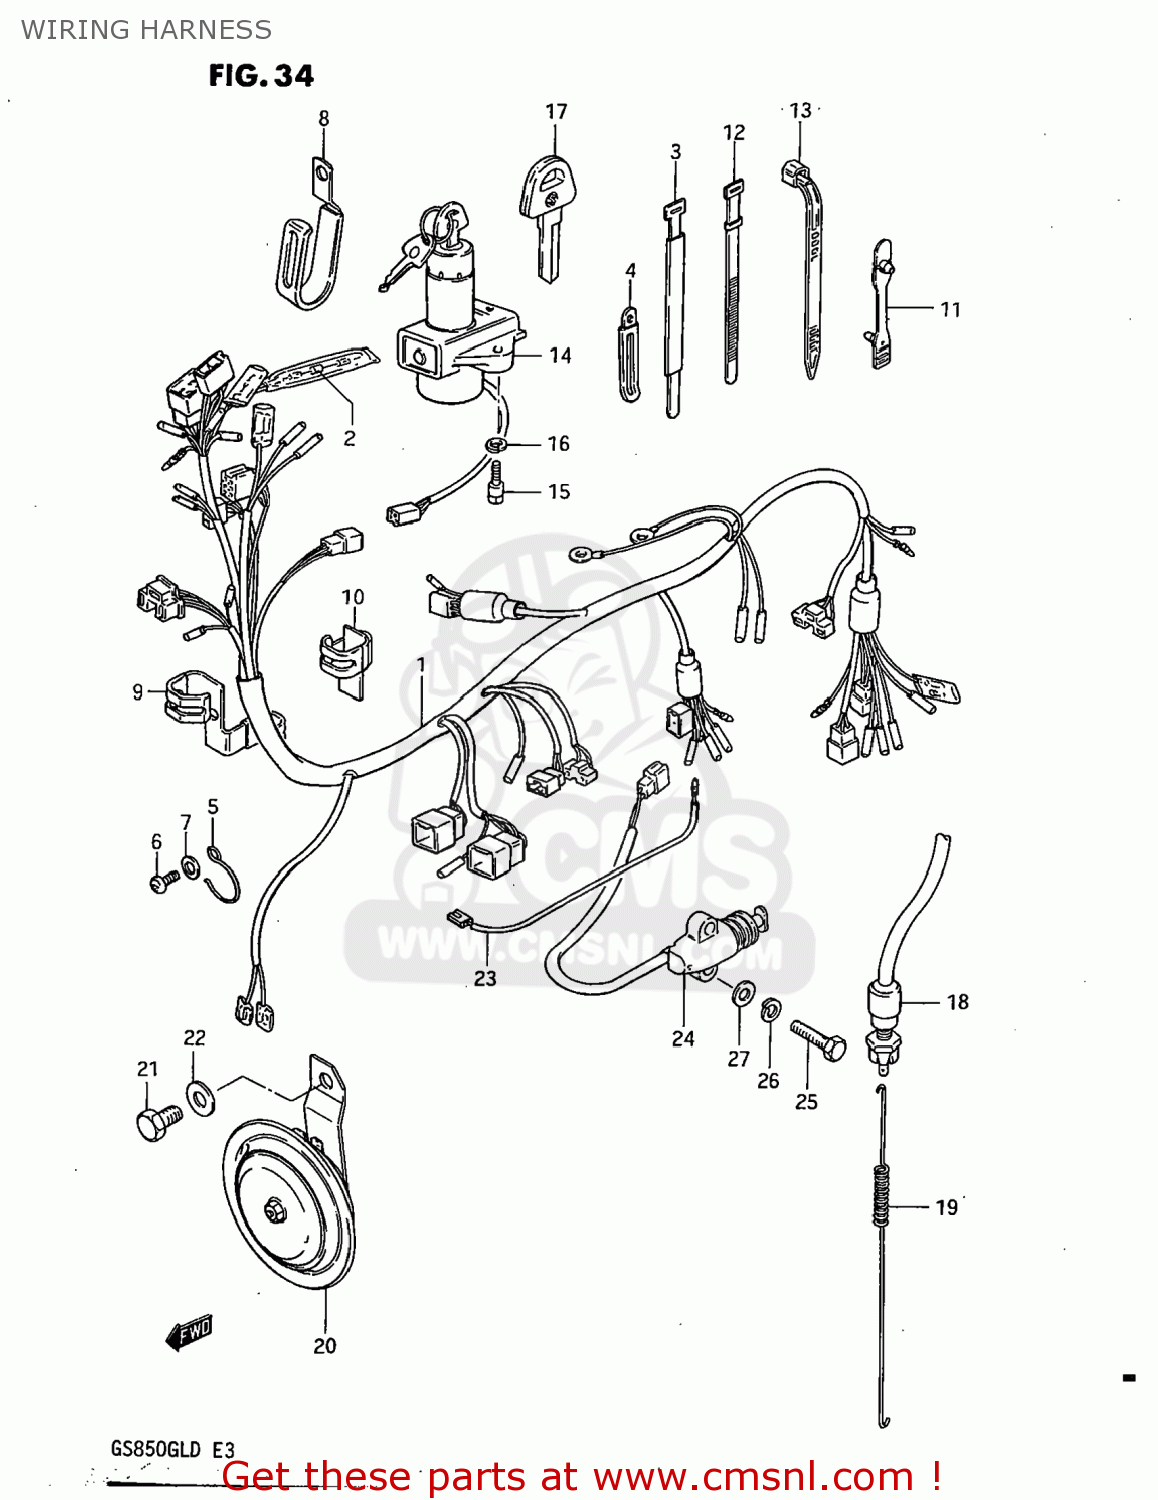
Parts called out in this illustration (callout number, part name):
1	HARNESS,WIRING
2	DIODE
3	CLAMP
4	CLAMP
5	GUIDE,WIRING HARNESS
6	SCREW 6X12
7	WASHER
8	CLAMP,WIRING HARNESS
9	CLAMP,WIRING HARNESS
10	CLAMP,WIRING HARNESS
11	CLAMP,L:88
12	CLAMP
13	CLAMP(L:125)
14	SWITCH ASSY,IGNITION
15	BOLT
16	LOCK WASHER
17	KEY,BLANK
18	SWITCH ASSEMBLY,STOP LAMP
19	SPRING
20	HORN ASSEMBLY
21	BOLT 8X12
22	WASHER
23	WIRE
24	SWITCH ASSEMBLY,SIDE STAND
25	BOLT
26	LOCK WASHER
27	WASHER
